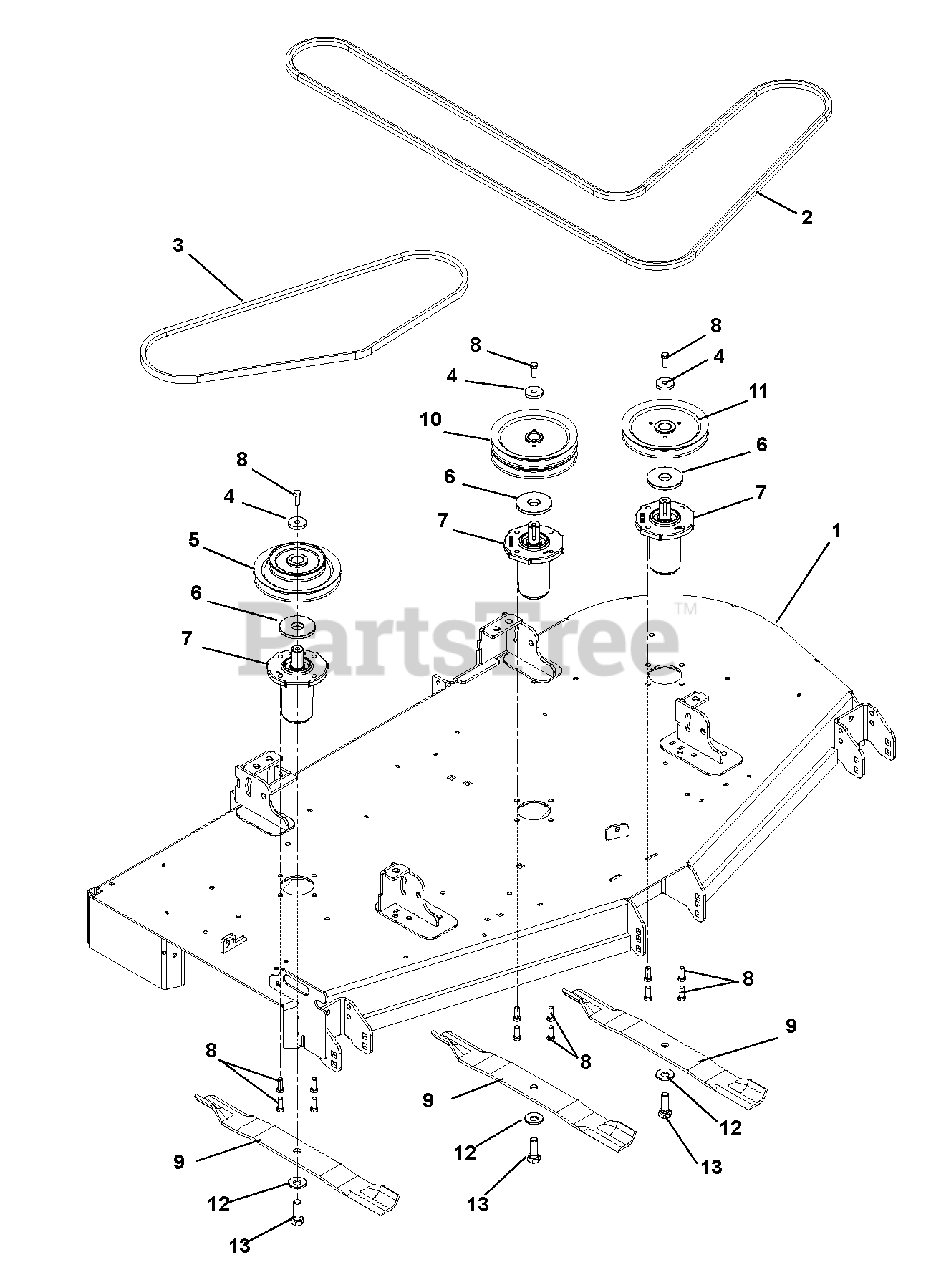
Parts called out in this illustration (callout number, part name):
1	Deck, 52"
2	Hex Belt, BB-Wrapped
3	V-Belt, B-Cogged
4	Washer, Flat Steel .406 x 1.50 x .245
5	Sheave, 1" ID x 6.00" OD and 3.50" OD
6	Retainer, Grease
7	Assembly, Spindle G3500
8	Bolt, Hex .38-16 x 1.00
9	Blade, 18.00" Mower (HI-LIFT)
10	Pulley, Double
11	Pulley, Single 1"ID x 6.00" OD
12	Washer, Bellville .63 x 1.625 x .14
13	Bolt, Hex .62-18 x 1.75 Grade 8
